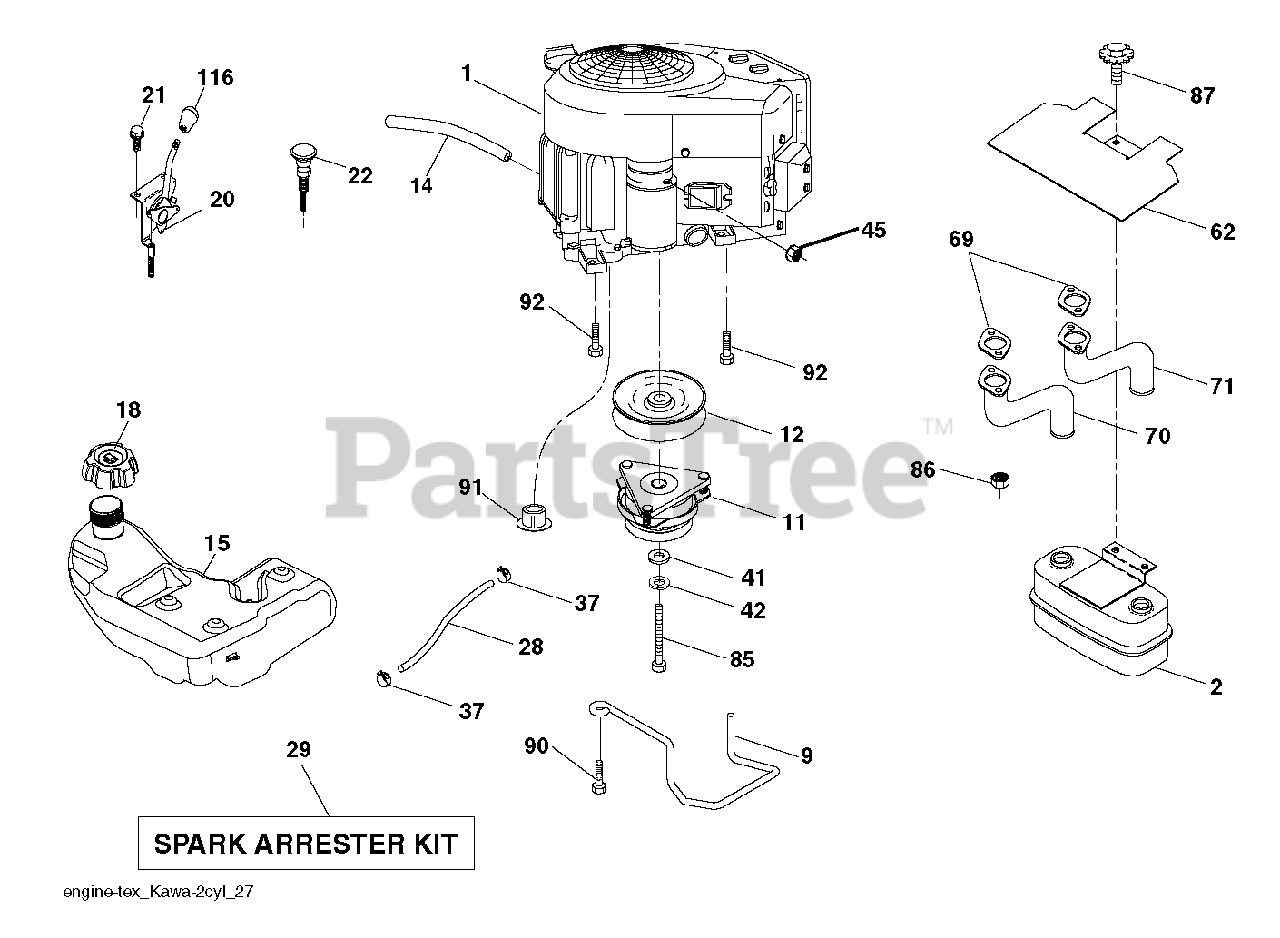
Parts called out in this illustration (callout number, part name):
2	MUFFLER.ASM.TWN.EXTNDED.DFLCTR
9	KEEPER BELT ENGINE
11	CLUTCH.ELECTRIC.LT.48"*
12	PULLEY.ENGINE.TUFFTORQ
14	TUBE, DRAIN OIL ASM.
15	TANK.ASSY.3.GAL.EPA
18	CAP.ASM.FL.RITCH.3"E10.SYM.498
20	CONTROL.THROTTLE.PRO.
21	SCREW.#10 X 0.750.BOS
22	CONTROL.CHOKE.ERGO.PUSH-IN.BLA
28	LINE.FUEL.64"REAR.EMIS
29	KIT.SPARK ARRESTOR 794945 B&S
37	HOSE CLAMP
42	LOCKWASHER
45	NUT
62	SHIELD.HEAT.MUFFLER
70	TUBE.EXHAUST.LH.FR961/FR730
71	TUBE.EXHAUST.RH.FR961/FR730
85	BOLT HEX 7/16-20X4-1/4"
86	NUT.HEX.FLANGE.TOPLOCK
87	Bolt, 5/16-18 X 1-3/4
90	SCREW 3/8-16X1
91	BUSHING.1.375OD
92	SCREW 3/8-16X1
